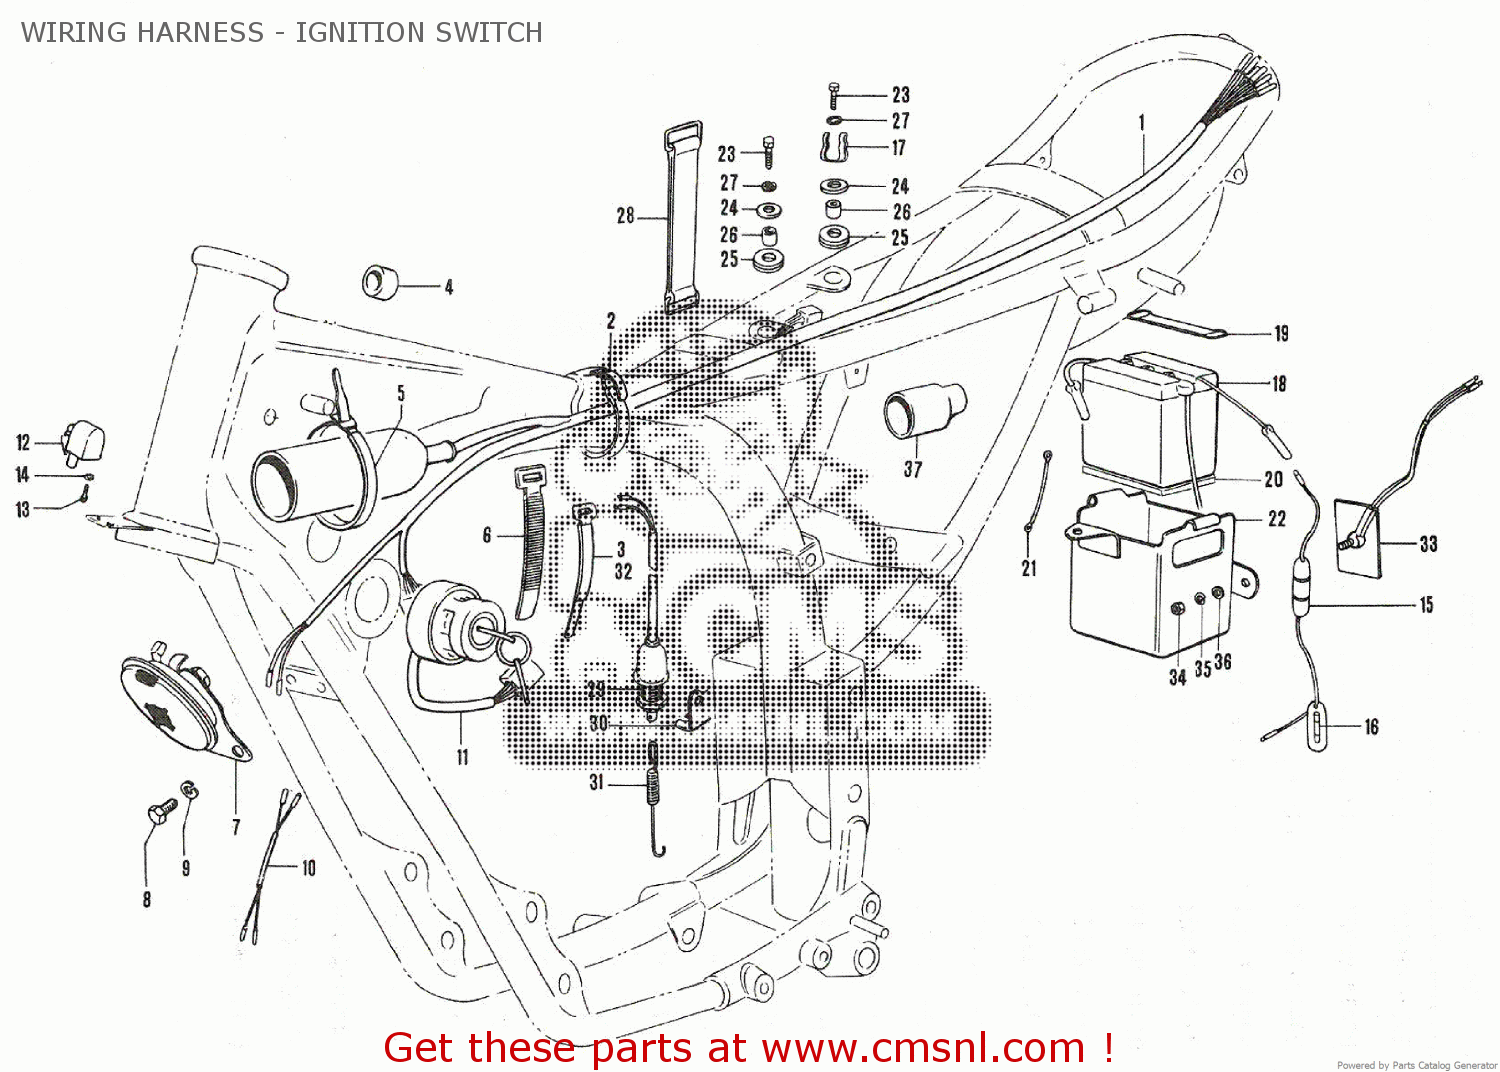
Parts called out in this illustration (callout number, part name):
1	WIRING HARNESS
2	CLAMP
3	CLAMP
4	WIRING HARNESS BAND
5	CLAMP
6	CLAMP
7	HORN ASSEMBLY
8	SMALL HEAD HEXAGON BOLT
9	LOCK WASHER
11	IGNITION SWITCH ASS'Y
12	LOCK ASSEMBLY,STEERING
13	SCREW
14	LOCK WASHER
15	BOX ASSEMBLY,FUSE
16	FUSE(15A)
17	HOLDER,FUSE CASE
18	BATTERY ASSY(6N4-2A4.2AH)
19	BAND
20	CUSHION,BATTERY
21	WIRE
22	HOLDER,BATTERY
23	BOLT
24	WASHER (6.5X20X1.2)
25	CUSHION
26	SPACER (7X9X7)
27	LOCK WASHER
28	BAND
29	SWITCH,BRAKE LAMP
30	BRAKE LAMP SWITCH BRACKET
31	SPRING
32	CLAMP
33	RECTIFIER ASSEMBLY
34	NUT
35	LOCK WASHER
36	WASHER
37	COVER,WIRING HARNESS
